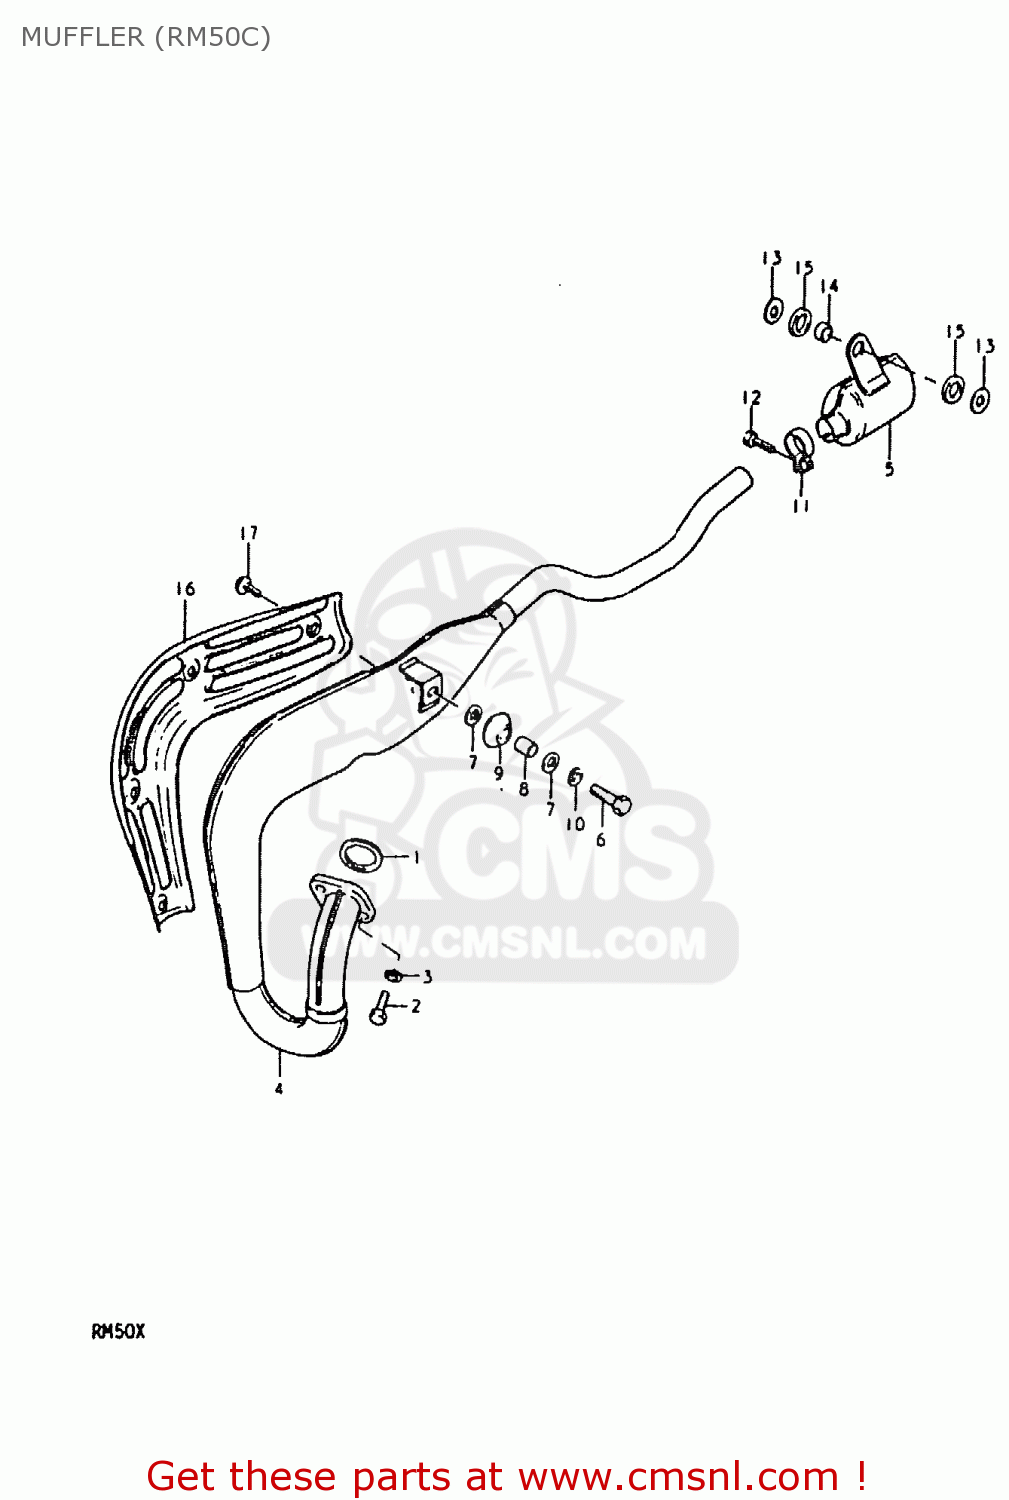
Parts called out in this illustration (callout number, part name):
1	GASKET,EXHAUST PIPE (NAS)
2	BOLT
3	LOCK WASHER
4	BODY,MUFFLER
5	BODY,MUFFLER
6	BOLT (8X30)
7	WASHER (8.7X22X2)
8	SPACER (8X12X15)
9	DAMPER,MUFFLER,FR
10	LOCK WASHER
11	CLAMP
12	BOLT(6X20)
13	WASHER
14	SPACER (8.6X13.8X9)
15	CUSHION
16	COVER,MUFFLER
17	SCREW
